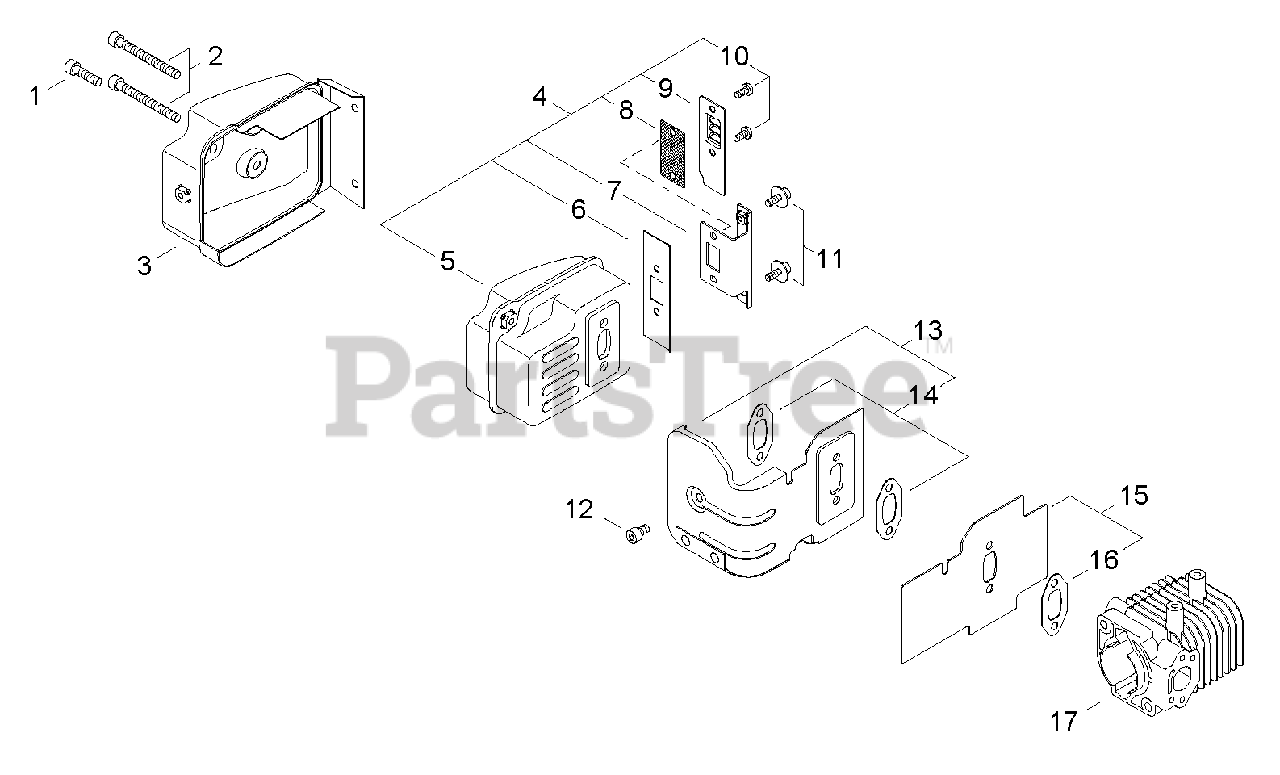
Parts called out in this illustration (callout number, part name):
1	BOLT CB-5×20
2	BOLT M5
3	COVER, MUFFLER
4	MUFFLER ASSY
5	MUFFLER
6	PLATE, MUFFLER
7	STAY, MUFFLER
8	SCREEN, SPARK ARRESTER
9	OUTLET, EXHAUST
10	SCREW 4×8
11	SCREW M4×8
12	BOLT 5×8
13	DEFLECTOR ASSY, EXHAUST HEAT
14	GASKET, EXHAUST
15	SHIELD ASSY, EXHAUST HEAT
16	GASKET, EXHAUST
17	CYLINDER
